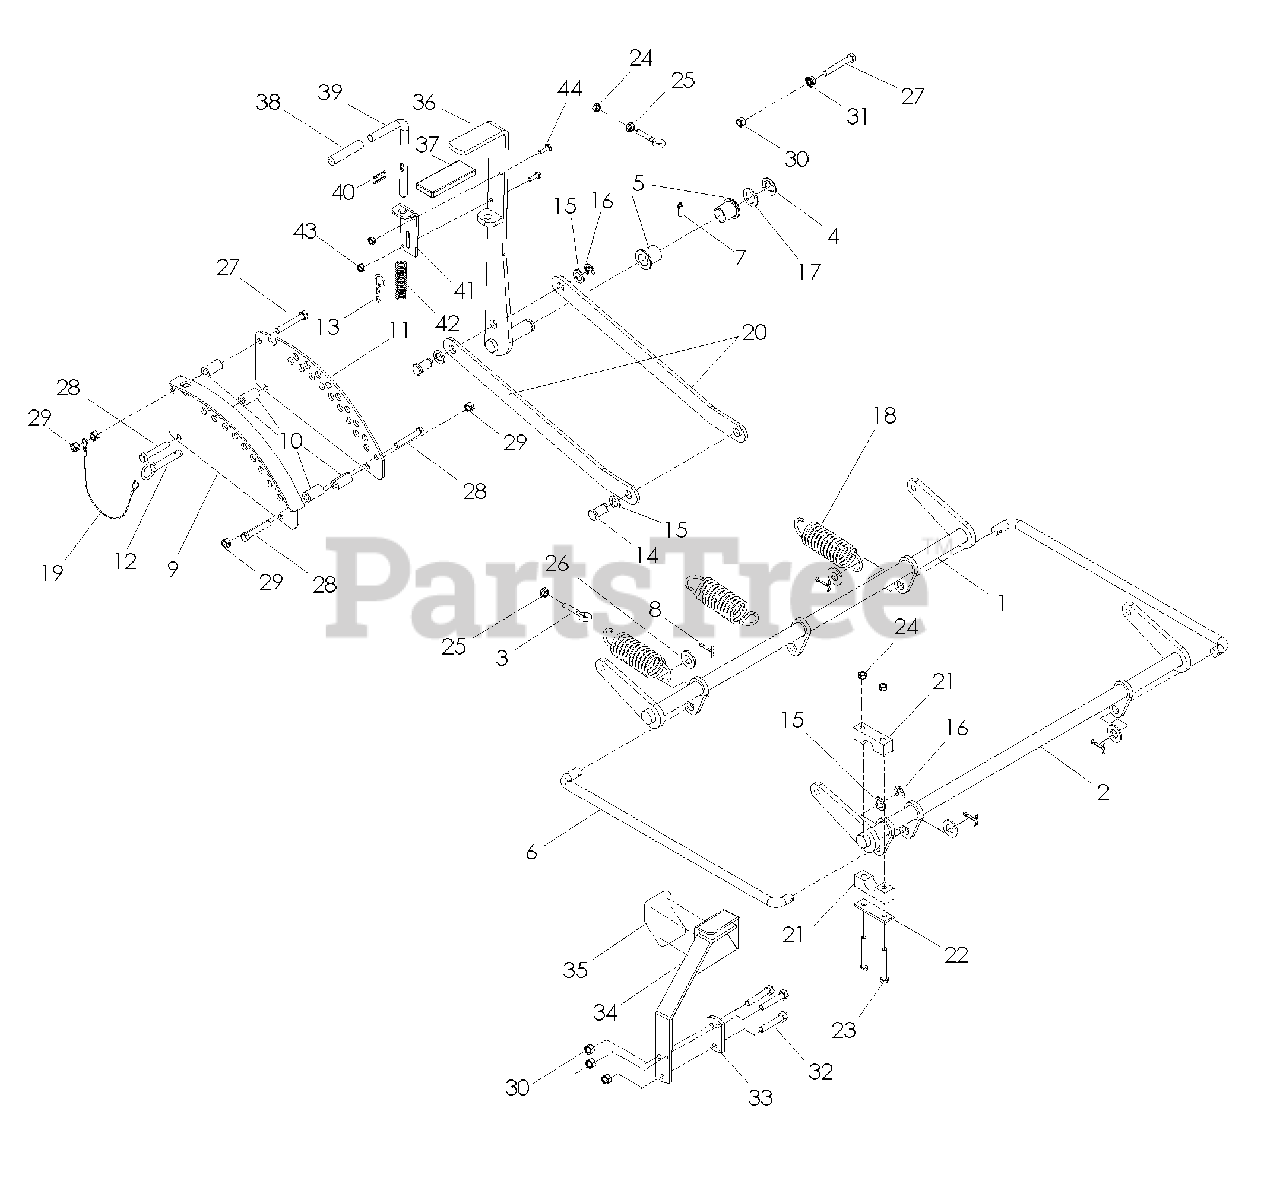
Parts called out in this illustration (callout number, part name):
1	LIFT SHAFT ASSEM, REAR
2	LIFT SHAFT ASM, FRONT
4	E-RING .875
5	BUSHING, FLANGED
6	CONNECTING LINK
7	ZERK, LONG
8	COTTER PIN 5/32 x 1 1/4
9	ADJUSTMENT PLATE
11	ADJUSTMENT PLATE
14	CLEVIS PIN
15	BUSHING, .625 MACHINE
16	E-RING .625
17	BUSHING, .875 MACHINE
18	SPRING, EXTENSION
20	LIFT LINKAGE
21	PILLOW BLOCK
22	REINFORCEMENT BAR
23	HCS 5/16-18 x 2 1/2
24	NUT 5/16-18 HEX CTRLK
25	NUT 5/16-18 WHIZ
26	WASHER 5/8 SAE FLAT
27	HCS 3/8-18 x2 1/2
28	HCS 3/8-16 x2 1/4
29	NUT 3/8-16 HEX CTRLK
30	NUT 3/8-16 HEX NYLOC
31	NUT 3/8-16 HEX WHIZLK
32	HCS 3/8-16 x 1 1/2
33	PLATE, TIGHTENING
34	LIFT PEDAL
35	PAD, ANTI-SKID
36	LIFT LEVER WLDMT
37	HANDLE CUSHION
38	VINYL GRIP
39	L PIN 1/2 x 6 1/2
40	PIN, GROOVED
41	PIN MOUNT, UPPER
42	SPRING,COMPRESSION
43	NUT 1/4-20 HEX CTRLK
44	HCS 1/4-20 x 3/4
